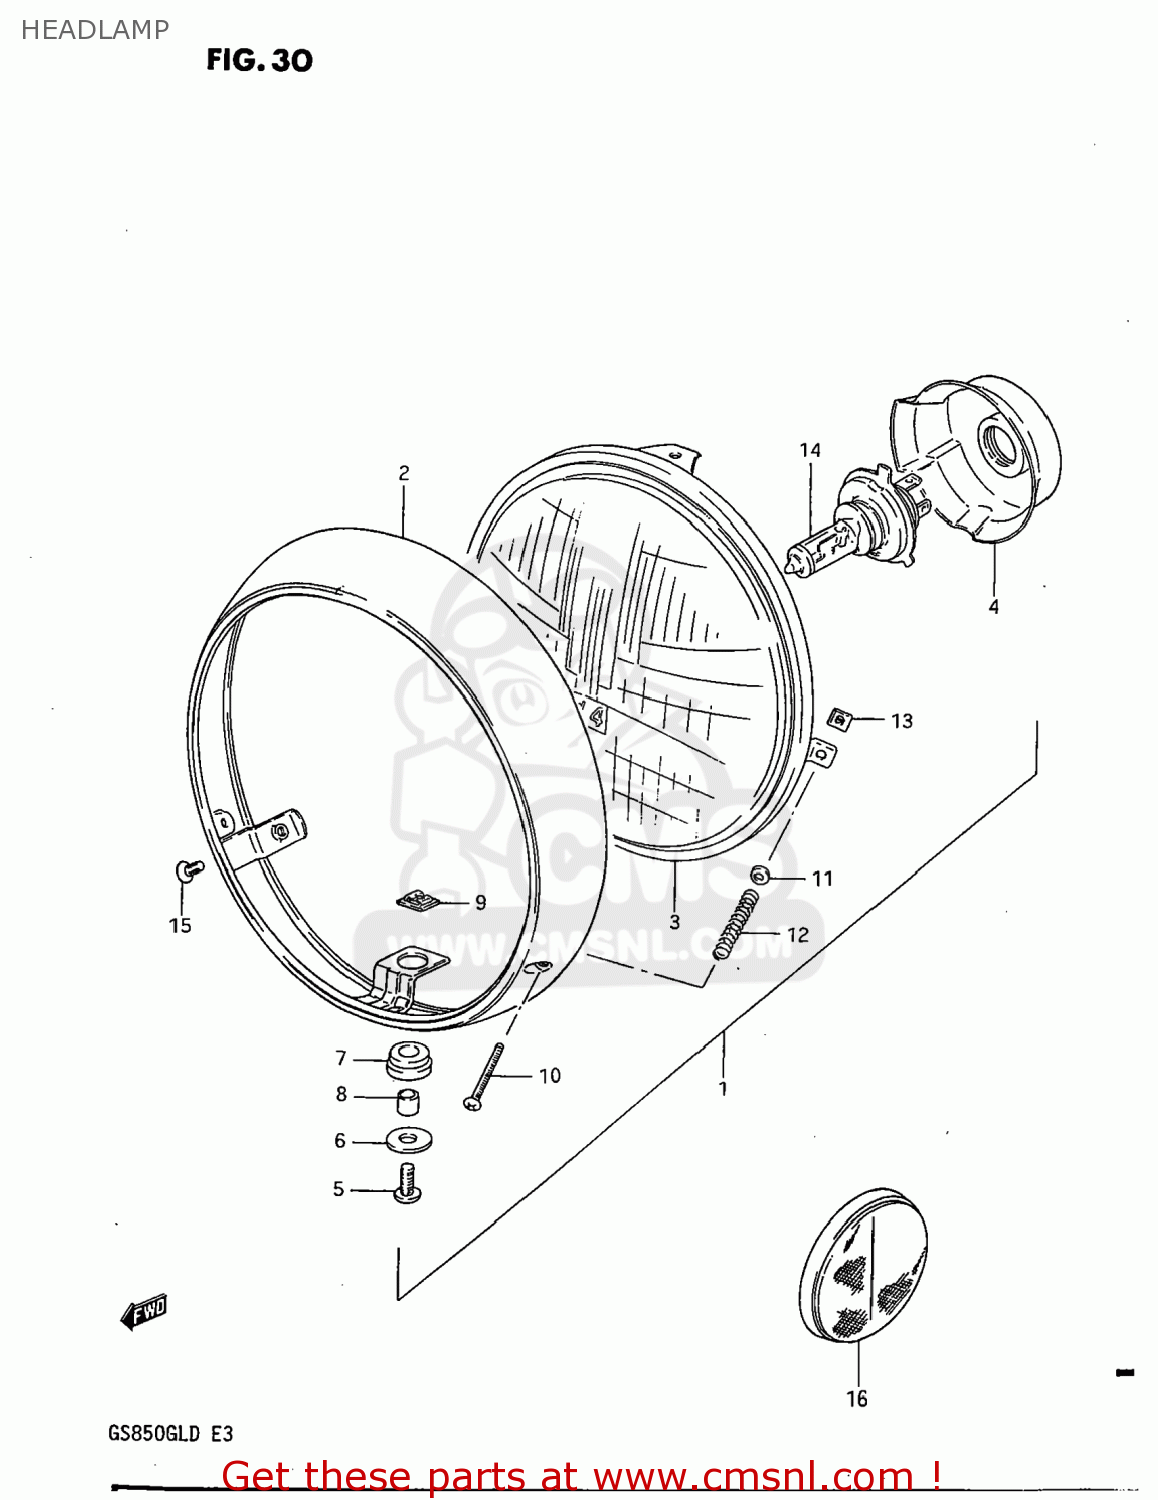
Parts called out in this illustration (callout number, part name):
1	HEADLAMP ASSEMBLY
2	RIM
3	LAMP UNIT
4	COVER,SOCKET
5	SCREW
6	WASHER
7	CUSHION
8	SPACER
9	NUT
10	SCREW
11	WASHER
12	SPRING
13	NUT,HEADLAMP ADJUSTER
14	BULB(12V60/55W,H4)
15	SCREW(5X12)
16	REFLEX REFLECTOR,RR
